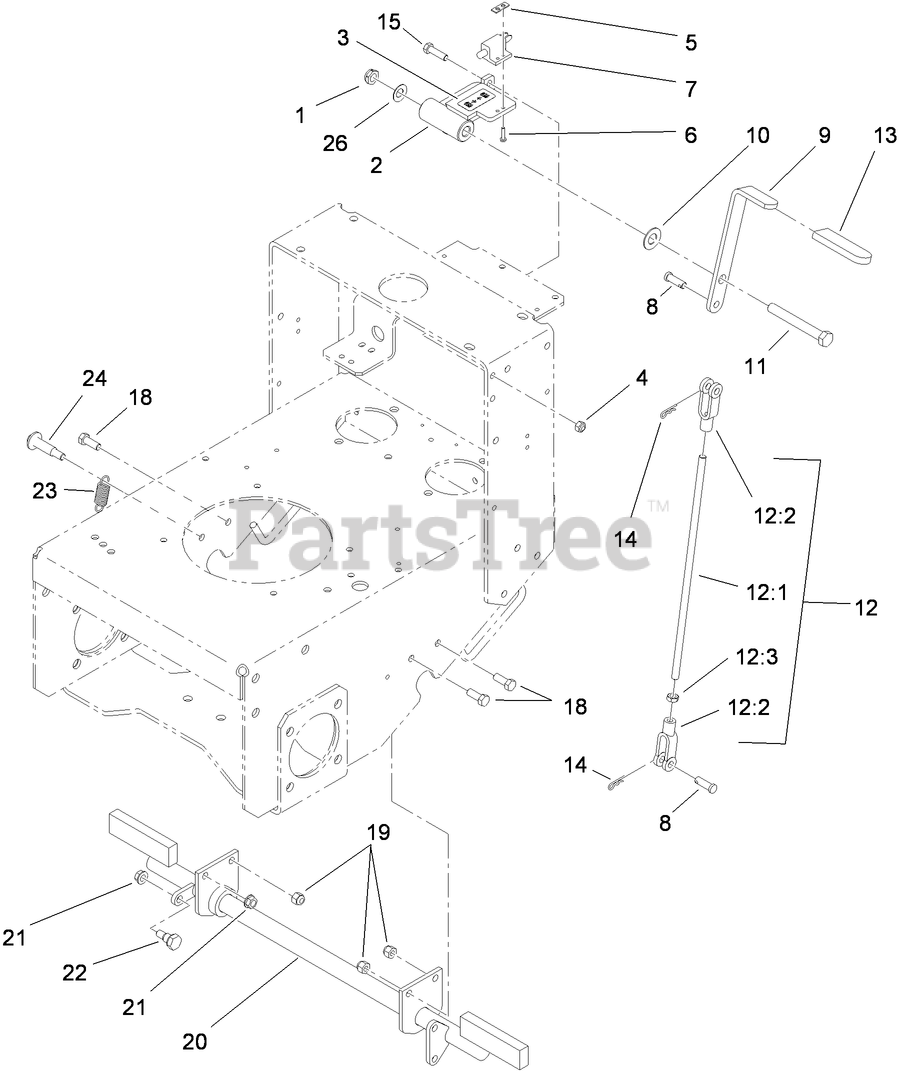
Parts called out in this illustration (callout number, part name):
1	NUT-LOCK, NI
2	SUPPORT-HANDLE
3	DECAL-BRAKE
4	NUT-LOCK, NI
5	PLATE-TAPPED
6	SCREW-HWH
7	SWITCH-CLOSED, NORMALLY
8	PIN-CLEVIS
9	HANDLE-BRAKE
10	BEARING-THRUST
11	SCREW-HH
12	BRAKE ROD ASM
12:1	ROD-BRAKE
12:2	YOKE-LINKAGE, BRAKE
12:3	NUT-HEX
13	GRIP-LEVER
14	PIN-COTTER
15	SCREW-HH
18	SCREW-HH
19	NUT-LOCK, NI
20	SHAFT-BRAKE, PARKING
21	NUT-HHF, WHIZ
22	BOLT-SHOULDER
23	SPRING-BRAKE
24	BOLT-WHEEL
26	WASHER-SPRING, CONICAL
